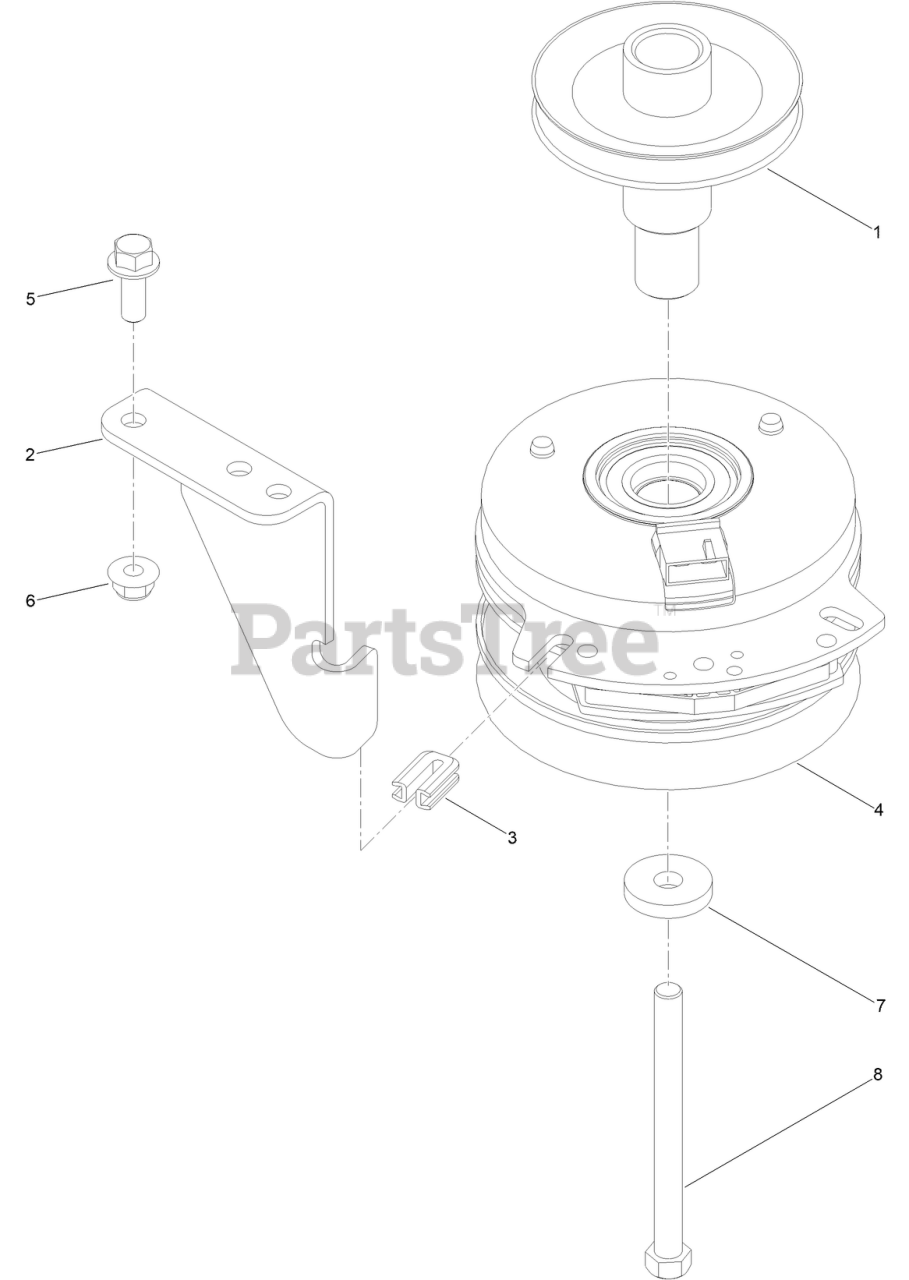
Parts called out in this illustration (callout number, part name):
1	PULLEY-ENGINE
2	STOP-CLUTCH (WIDE)
3	ISOLATOR-CLUTCH
4	CLUTCH-PTO
5	SCREW-HHF
6	NUT-HF, NI
7	WASHER
8	SCREW-HH
